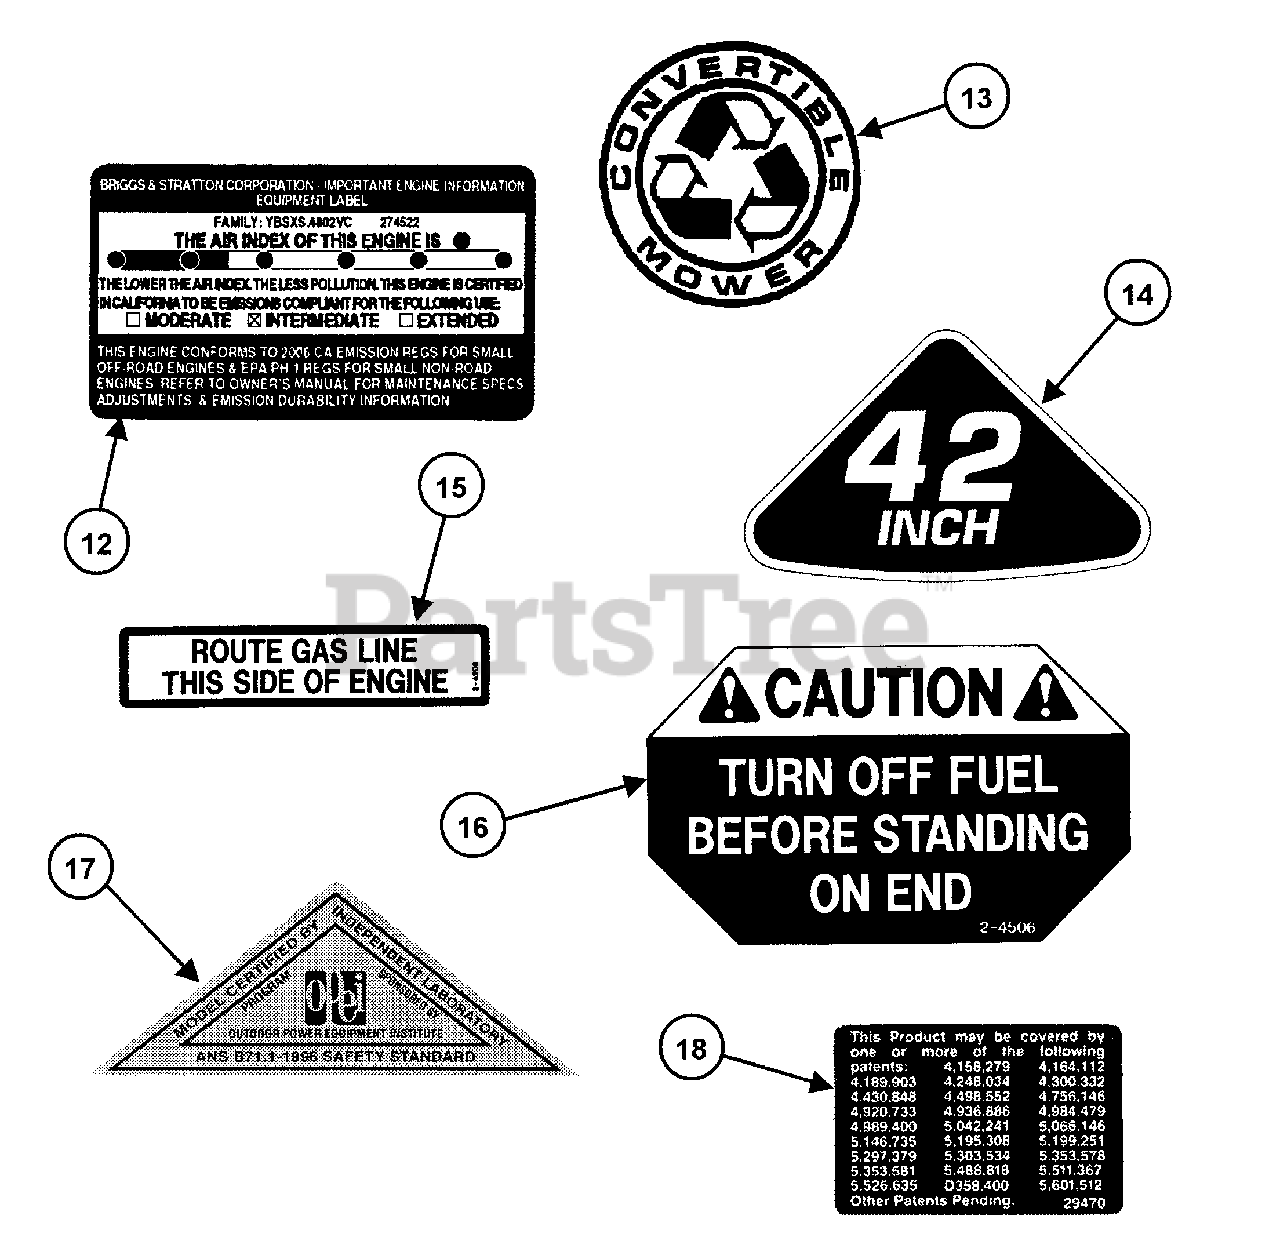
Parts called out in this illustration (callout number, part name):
12	DECAL, B&S Air Index/Emission Label
13	LOGO, Convertible (Blue)
14	DECAL, 42 Inch
15	DECAL, Fuel Routing
16	DECAL, Fuel Shut-Off
17	DECAL, OPEI Ride On
18	DECAL, Patent Numbers
